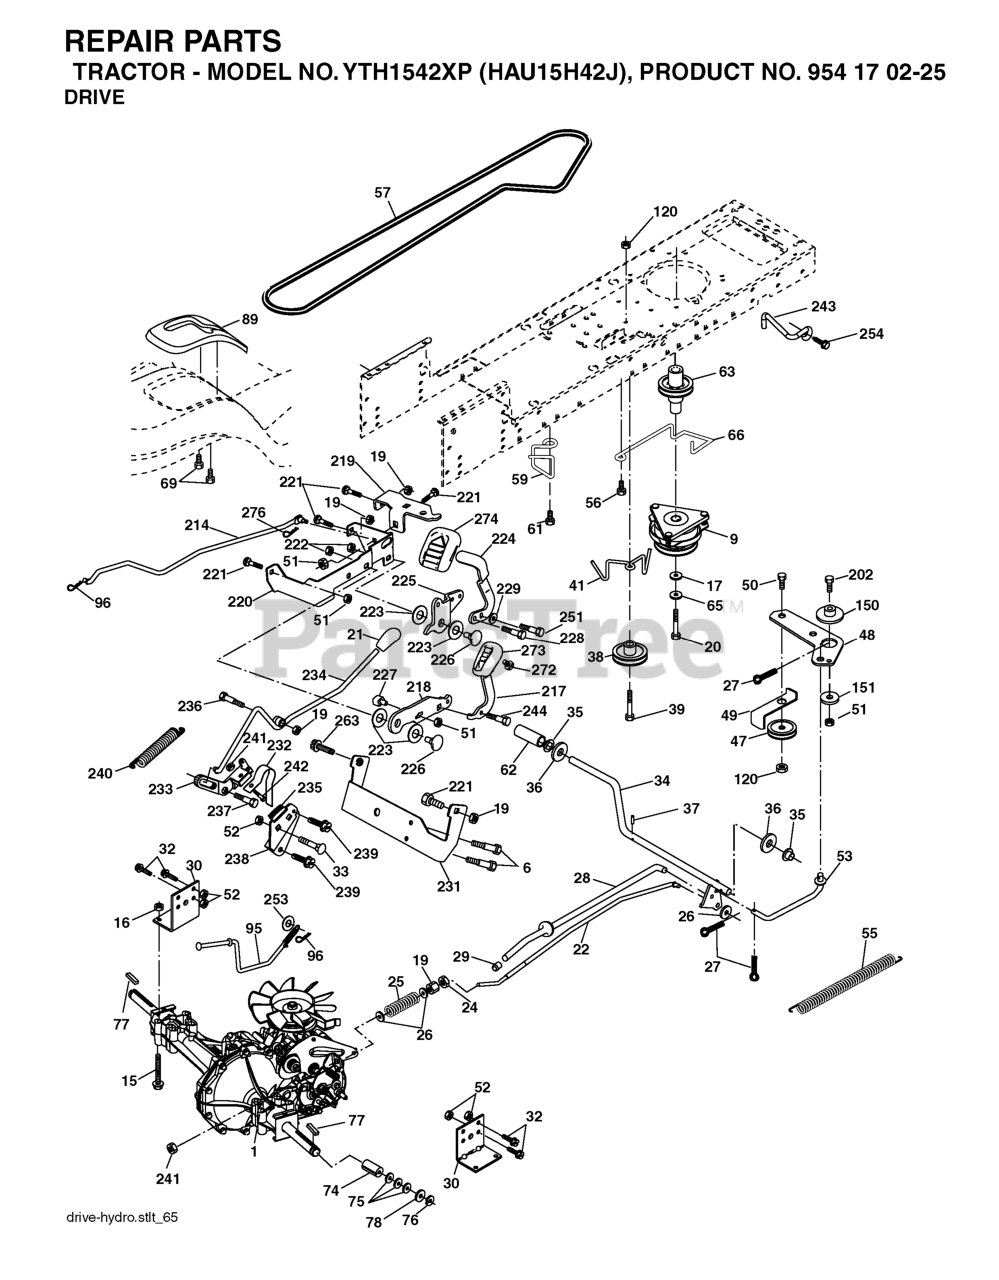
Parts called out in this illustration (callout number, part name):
6	SCREW 5/16"
9	RB.CLUTCH.OGURA.4.4.PD
15	BOLT HEX 5/16-18 GR 5
16	NUT.71038.31-18.HEX.NYLOCK
19	NUT
20	BOLT HEX 7/16-20X4-1/4"
22	ROD.BRAKE.HG-0510.PEDAL.CONTRL
24	NUT
25	SPRING BRAKE ROD
26	WASHER
27	COTTER PIN
28	ROD, PARKING BRAKE
29	PLUNGER CAP
30	BRKT, TRNSXLE MNT 20"
32	BOLT
33	RP BOLT 5/16-18 X3/4 ZN/YEL GR
34	SHAFT, FOOT PEDAL
35	BEARING.NYLON
37	DRIVE PIN
38	PULLEY IDLER COMPOSITE
41	KEEPER, BELT IDLER
47	IDLER PULLEY
48	BELLCRANK, CLUTCH
49	RETAIN BELT
50	BOLT.3/8-16X1.50
52	LOCKNUT
53	LINK, CLUTCH LT
55	SPRING, RETURN LT
56	SCREW.3/8-16
57	DRIVE BELT, LTH & YTH TRACTORS
59	KEEPER, BELT CENTER
61	SCREW 3/8-16X.875
62	PEDAL COVER T
63	PULLEY- ENGINE
64	BOLT HEX 7/16-20X4-1/4"
65	LOCKWASHER
66	KEEPER BELT ENGINE
69	SCREW.HI-LO.CONSOLE
74	SPACER AXLE
77	SQUARE KEY
95	ROD BYPASS
96	RETAINER M
120	NUT LOCK FLG 3/8-16 UNC
150	SPACER, RETAINER
151	WASHER 12/32X2X10GA
214	LINK TRANSAXLE
217	PEDAL REVERSE
218	ARM CONTROL PEDAL REVERSE
219	BRACKET FREST PDL
220	BRACKET MTG.PDL CONTROL
221	Bolt - Rd. Hd. Sq. Neckiage 3/8 16 x 3/4
222	Nut, Crownlock Hex 7/16-14 unc
223	WASHER NYLON
224	PEDAL FORWARD
225	ARM CONTROL PEDAL FORWARD
226	BOLT PIVOT SPACER
227	CAM REVERSE PEDAL LT
228	BOLT SHOULDER
229	WASHER.SERRATED.5/16X.75
231	STRAP TORQUE
232	ACUATOR CRUISE DISENGAGE
233	PAWL CONTROL CRUISE
234	LEVER CONTROL CRUISE
235	SECTOR CONTROL CRUISE
237	SHOULDER BOLT 5/16-18TT
238	ARM MTG.CRUISE SECTOR
239	Screw 5/16-18 x 1/2 Hex, Self Tapping 5/16-18 x 1/2
240	SPRING RETURN CRUISE CONTROL
241	NUT CENTERLOCK
242	BOLT
243	BRACKET, ANTI-ROTATION
244	CAPSCREW.HXHD.FLG.5/16-18X.625
251	SCREW 5/16-18X1
254	SCREW 3/8-16X1
263	SCREW, 3/8-16X3/4
272	SCREW, 5/16-18 X 1/2
274	COVER PEDAL FORWARD
276	CLIP RETAINER
